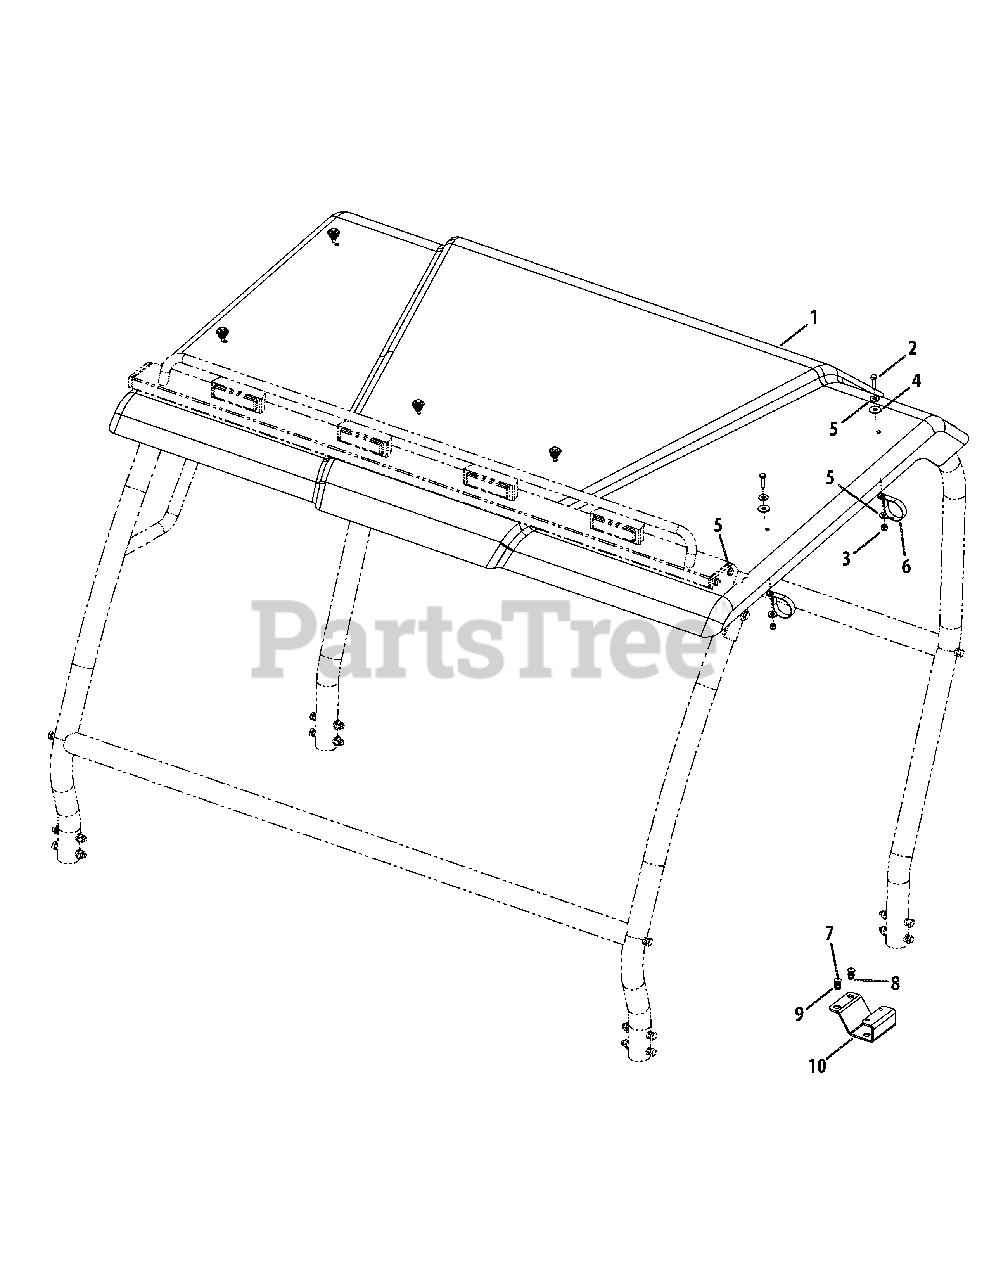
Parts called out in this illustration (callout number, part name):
1	Canopy, UV
2	SCREW 1/4-20 X1.00 GR5
7	Screw
8	Nut
9	Washer
10	Bracket
